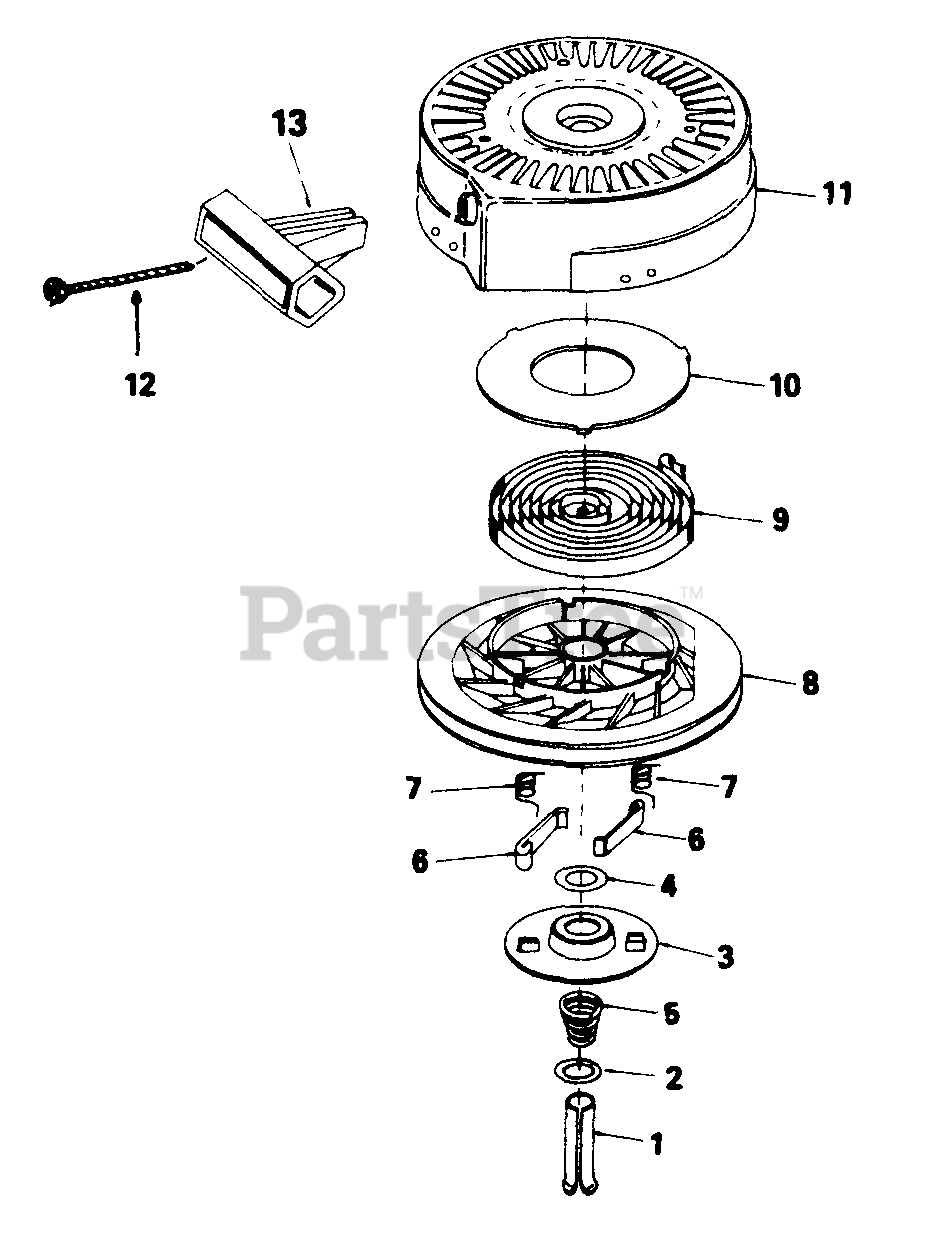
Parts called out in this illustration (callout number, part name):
1	Pin, Spring
5	Spring, Brake
6	Dog, Starter
7	Spring, Dog
9	Spring, Rewind
10	Cover, Spring
11	Housing Ass'y., Starter
12	Rope, Starter (Length 98" K 9/64" Dia.)
13	Handle, Starter
